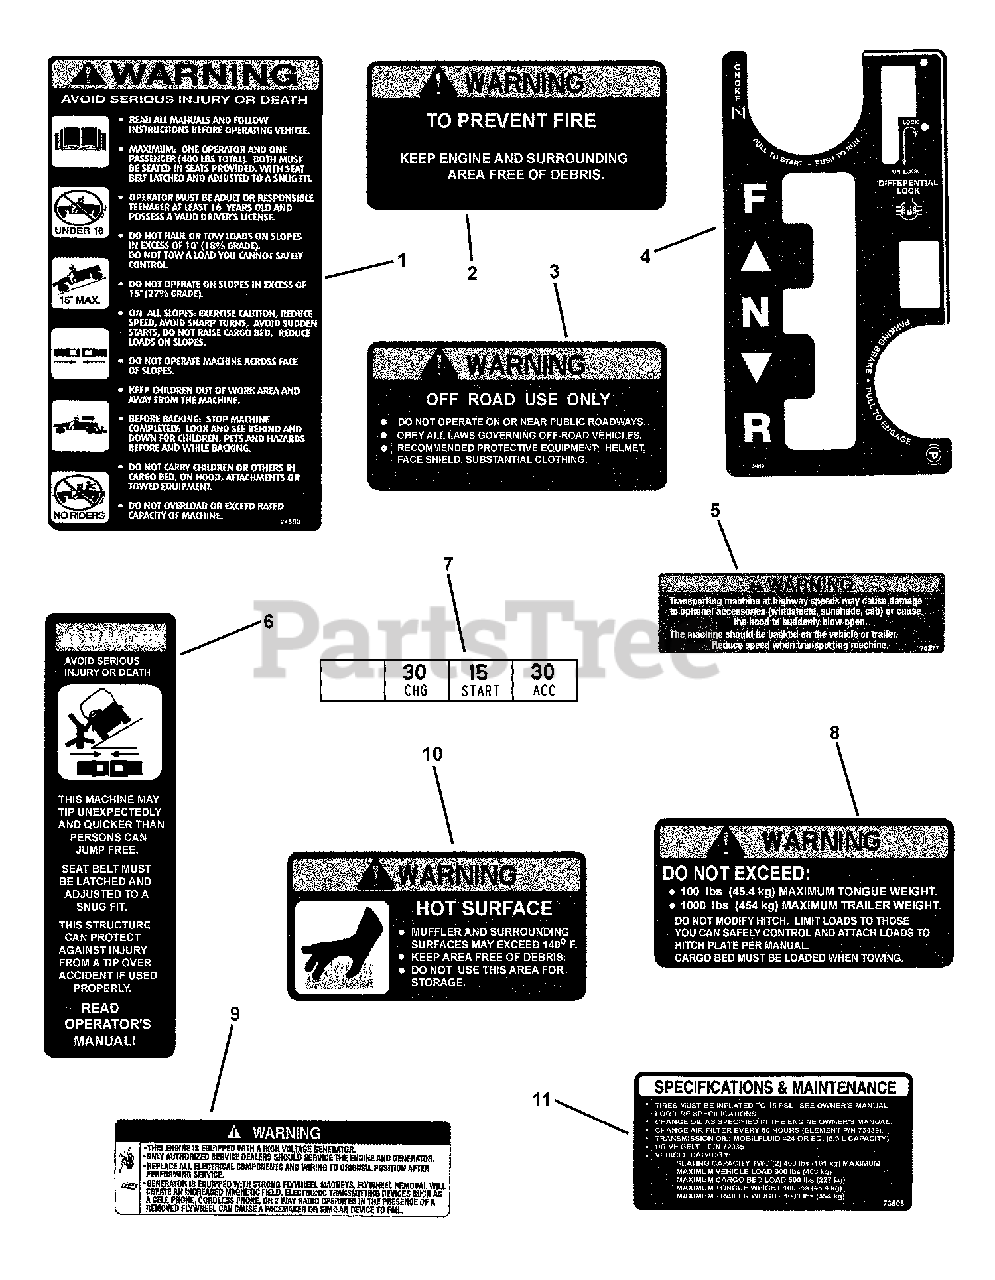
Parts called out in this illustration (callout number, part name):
1	DECAL, Warning Avoid Injury or Death
2	DECAL, Warning- To Prevent Fire
3	DECAL, Warning- Off Road Use Only
4	DECAL, Console
5	DECAL. Transport Warning
6	DECAL, Danger ROPS
7	DECAL, Fuse Box, Utility Vehicle
8	DECAL, Warning- Hitch Load
9	DECAL, Warning, B&S Powerlink
10	DECAL, Warning- Hot Surface
11	DECAL, Specs & Maintenance
